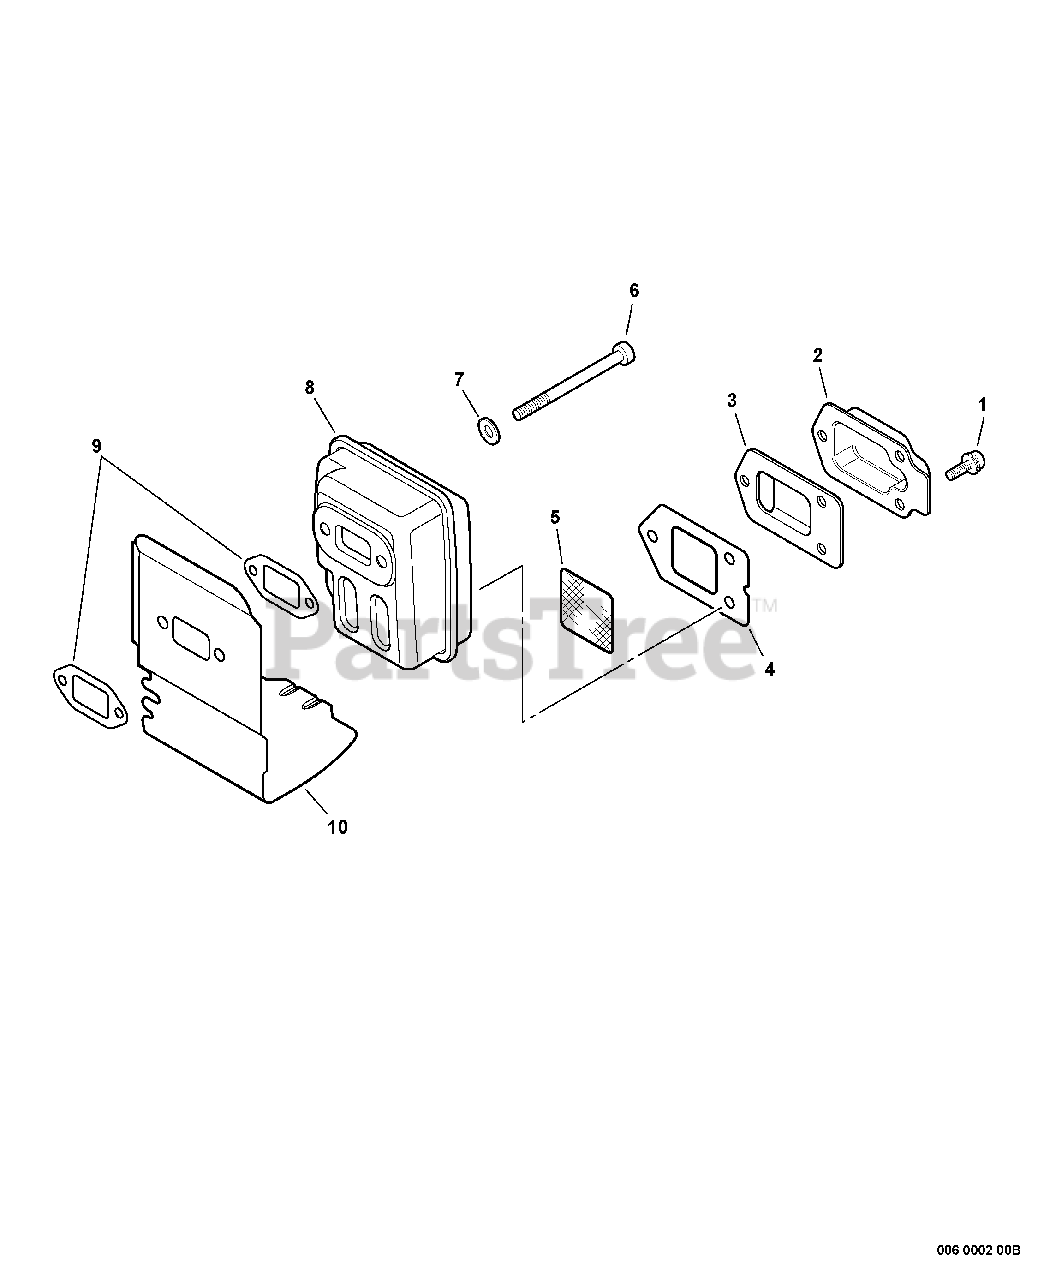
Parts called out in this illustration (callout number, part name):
1	SCREW - 4X10
2	GUIDE, EXHAUST - OUTER
3	GASKET, EXHAUST - INNER
4	GASKET, EXHAUST
5	SCREEN, SPARK ARRESTOR
6	SCREW - 5X55
7	WASHER - 5
9	GASKET, EXHAUST
10	SHIELD, EXHAUST
